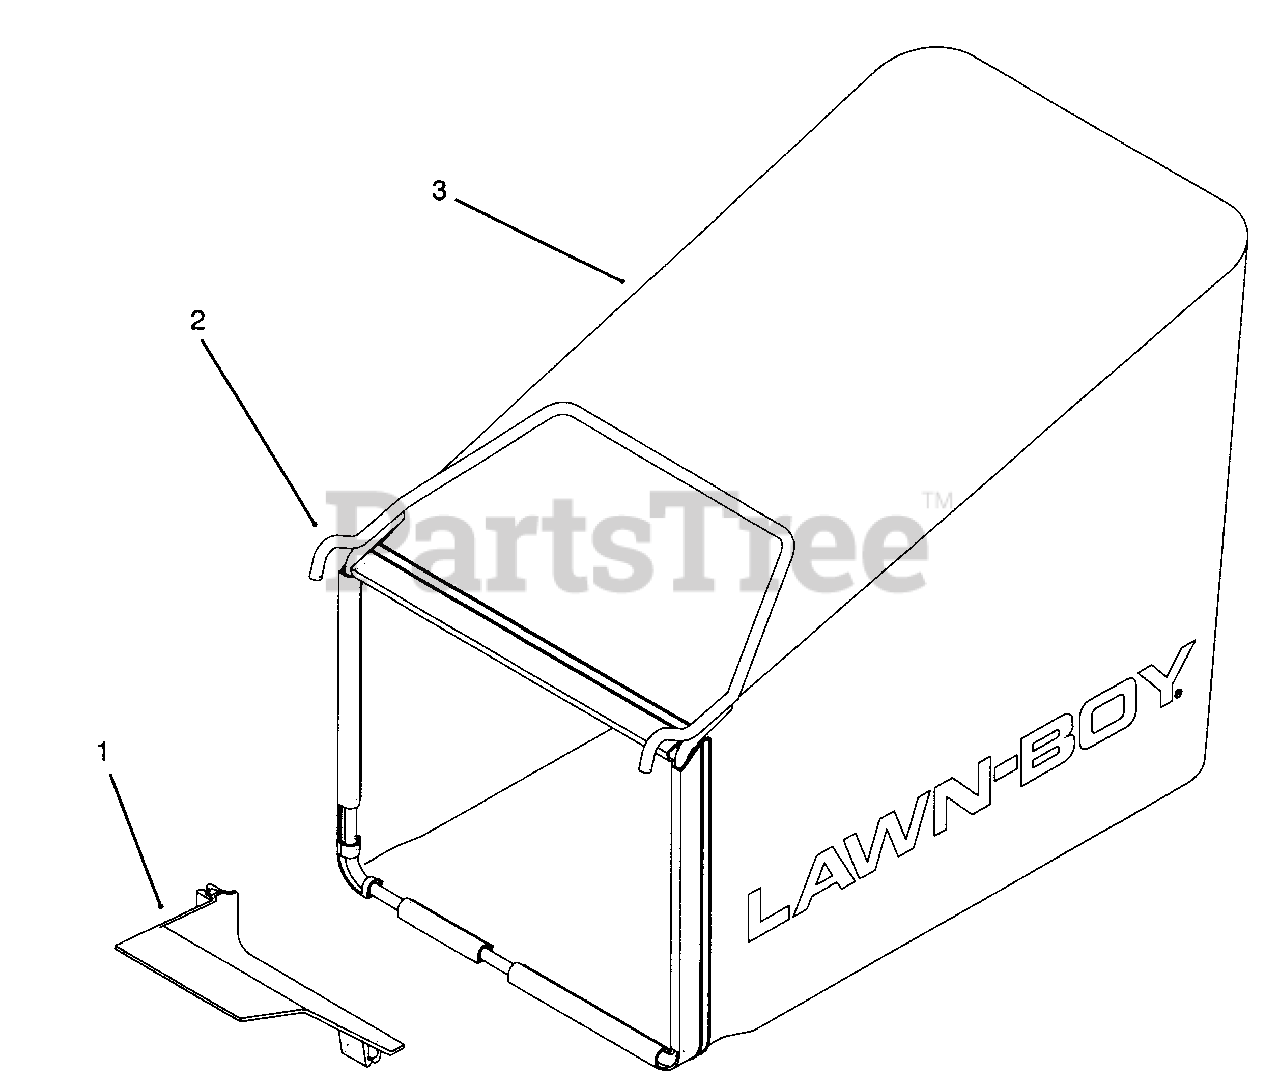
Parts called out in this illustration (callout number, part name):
1	Ramp-Grass Bag
2	Frame
3	Bag-Grass
